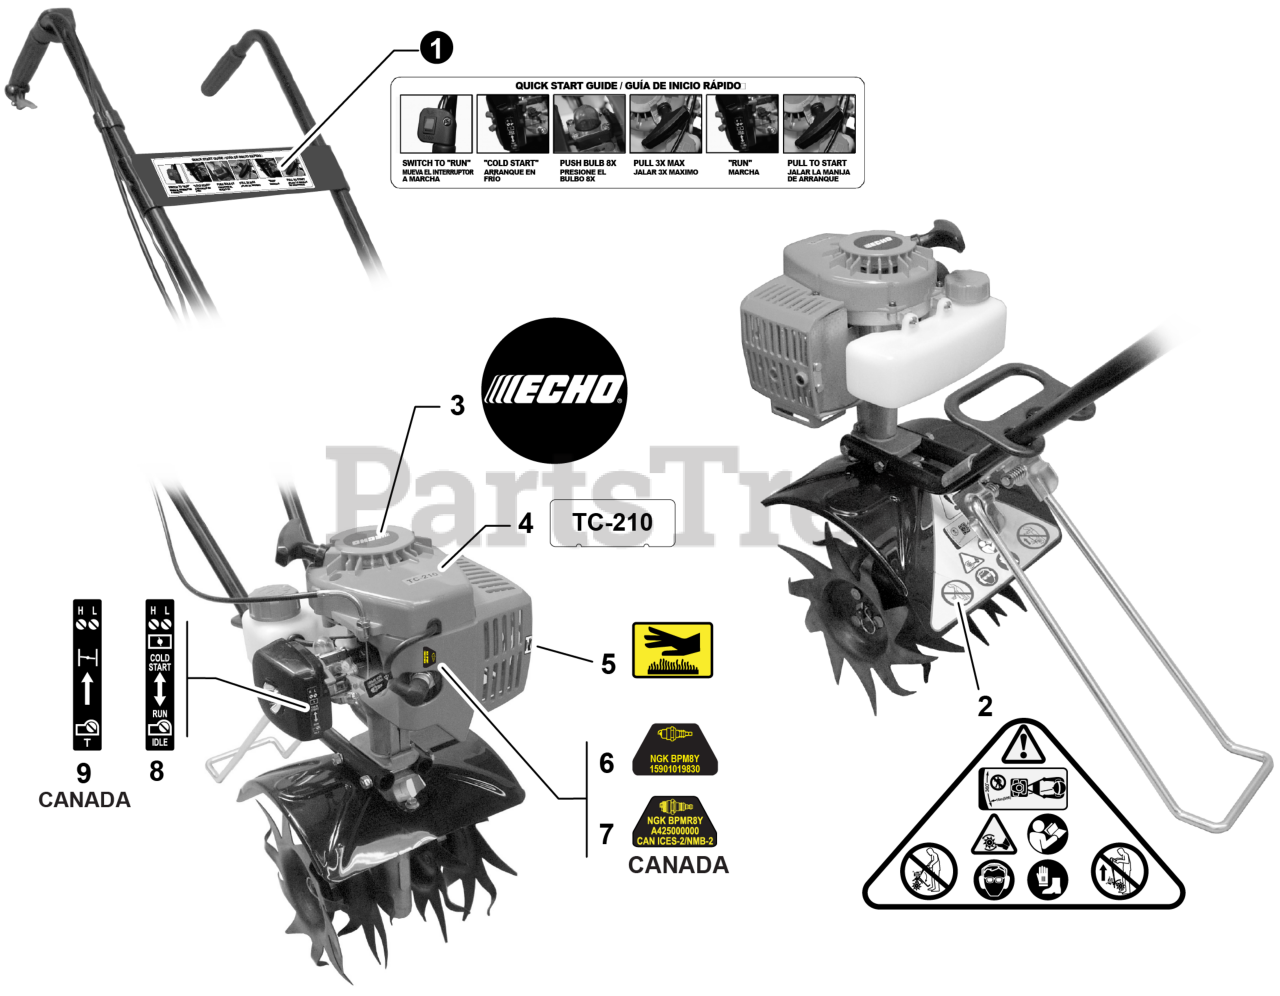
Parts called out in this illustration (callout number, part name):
1	LABEL - OPERATION
2	LABEL - CAUTION
3	LABEL - STARTER - ECHO
4	LABEL - MODEL
5	LABEL - CAUTION - HOT
6	LABEL - SPARK PLUG - BPM8Y
7	LABEL - SPARK PLUG - BPMR8Y
8	LABEL - CHOKE
9	LABEL - CHOKE
